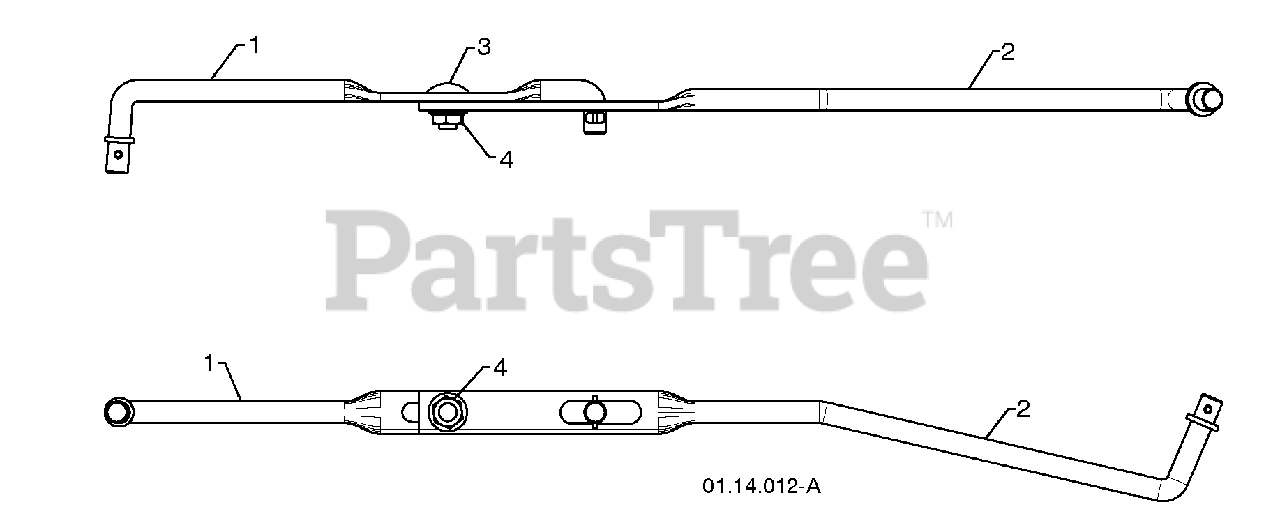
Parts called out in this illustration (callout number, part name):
1	Shifter Rod Top
2	Shifter Rod Bottom
3	Carriage Bolt 5/16-18 X .75
4	Nut 5/16-18
